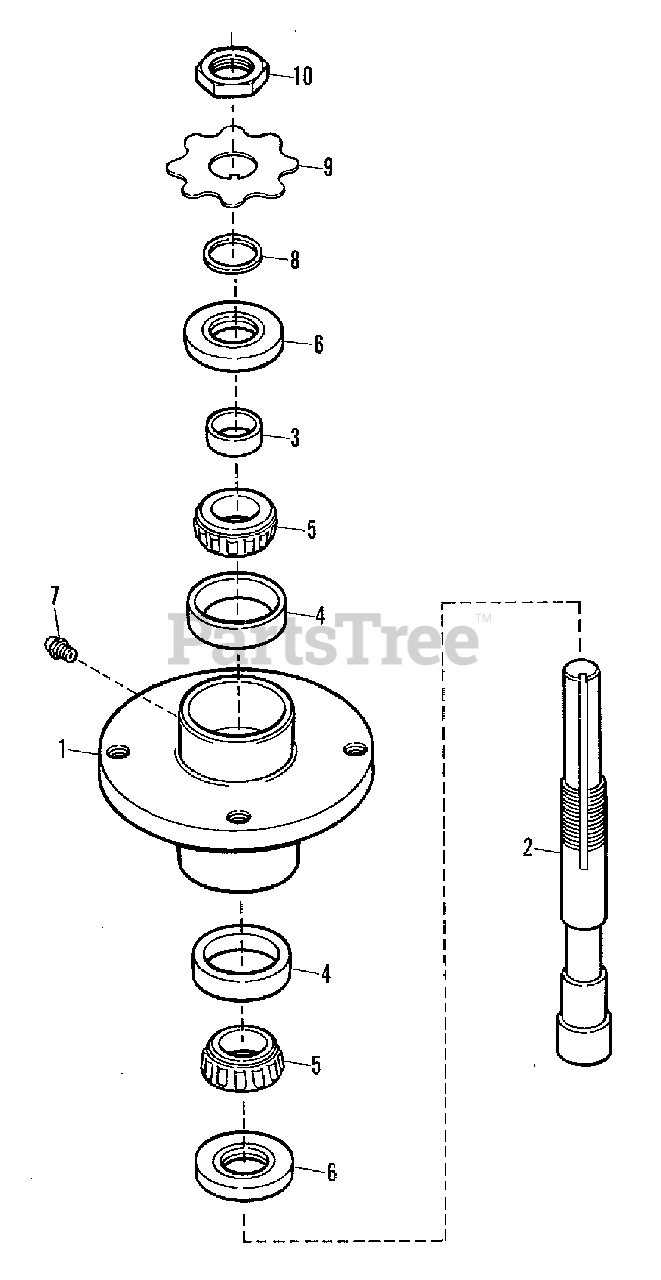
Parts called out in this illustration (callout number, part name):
1	HOUSING, Spindle
2	SHAFT, Spindle
3	SPACER, Top
4	CUP, Bearing
5	CONE, Bearing
7	FITTING, Lube, 1/4-28 Taper Thread
9	WASHER, Star
10	NUT, Jam, 13/16NF
